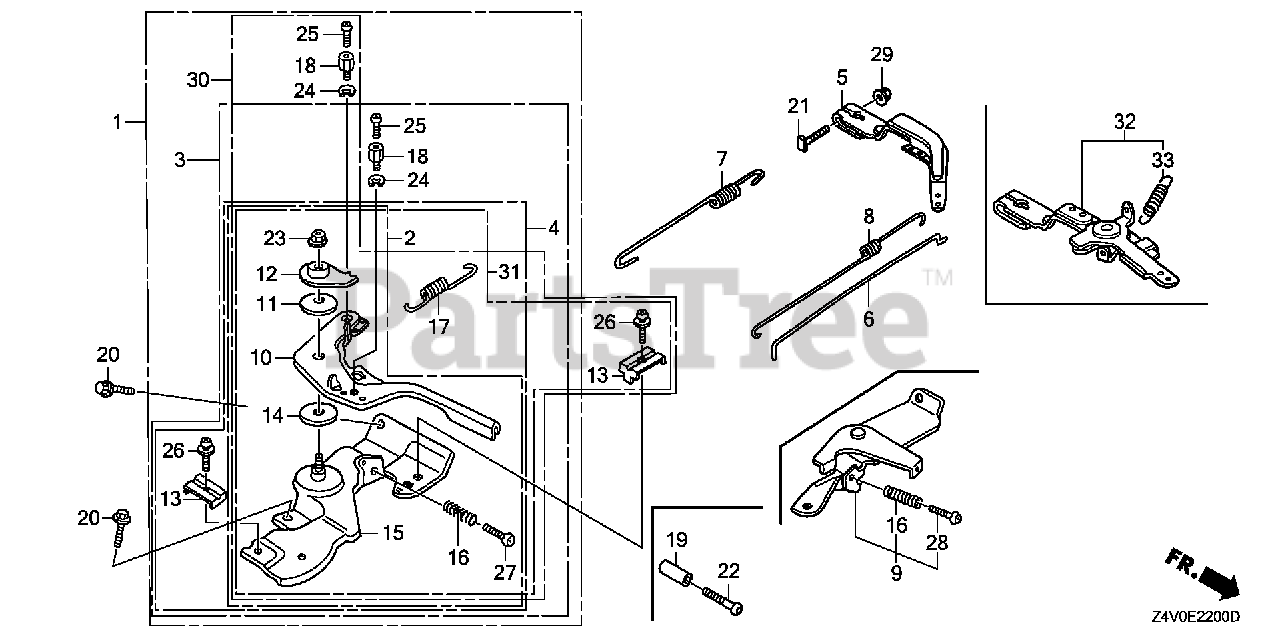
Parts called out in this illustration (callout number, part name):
4	CONTROL ASSY. (REMOTE)(COO)(FOR U.S.A.)
4	CONTROL ASSY. (REMOTE)
5	ARM, GOVERNOR
6	ROD, GOVERNOR
7	SPRING, GOVERNOR
8	SPRING, THROTTLE RETURN
10	LEVER, CONTROL
11	SPRING, LEVER
12	WASHER, CONTROL LEVER
13	HOLDER, CABLE
14	SPACER, CONTROL LEVER
15	BASE, CONTROL
16	SPRING, CONTROL ADJUSTING Use from Engine SN 2327377.
17	SPRING, CABLE RETURN
19	COLLAR, STOPPER
20	BOLT, FLANGE (6X12) (CT200)
21	BOLT, GOVERNOR ARM
22	SCREW, RECESSED (5X25)
23	NUT, SELF-LOCK (6MM)
26	SCREW, PAN (5X16)
27	SCREW, PAN (5X25)
29	NUT, FLANGE (6MM)
